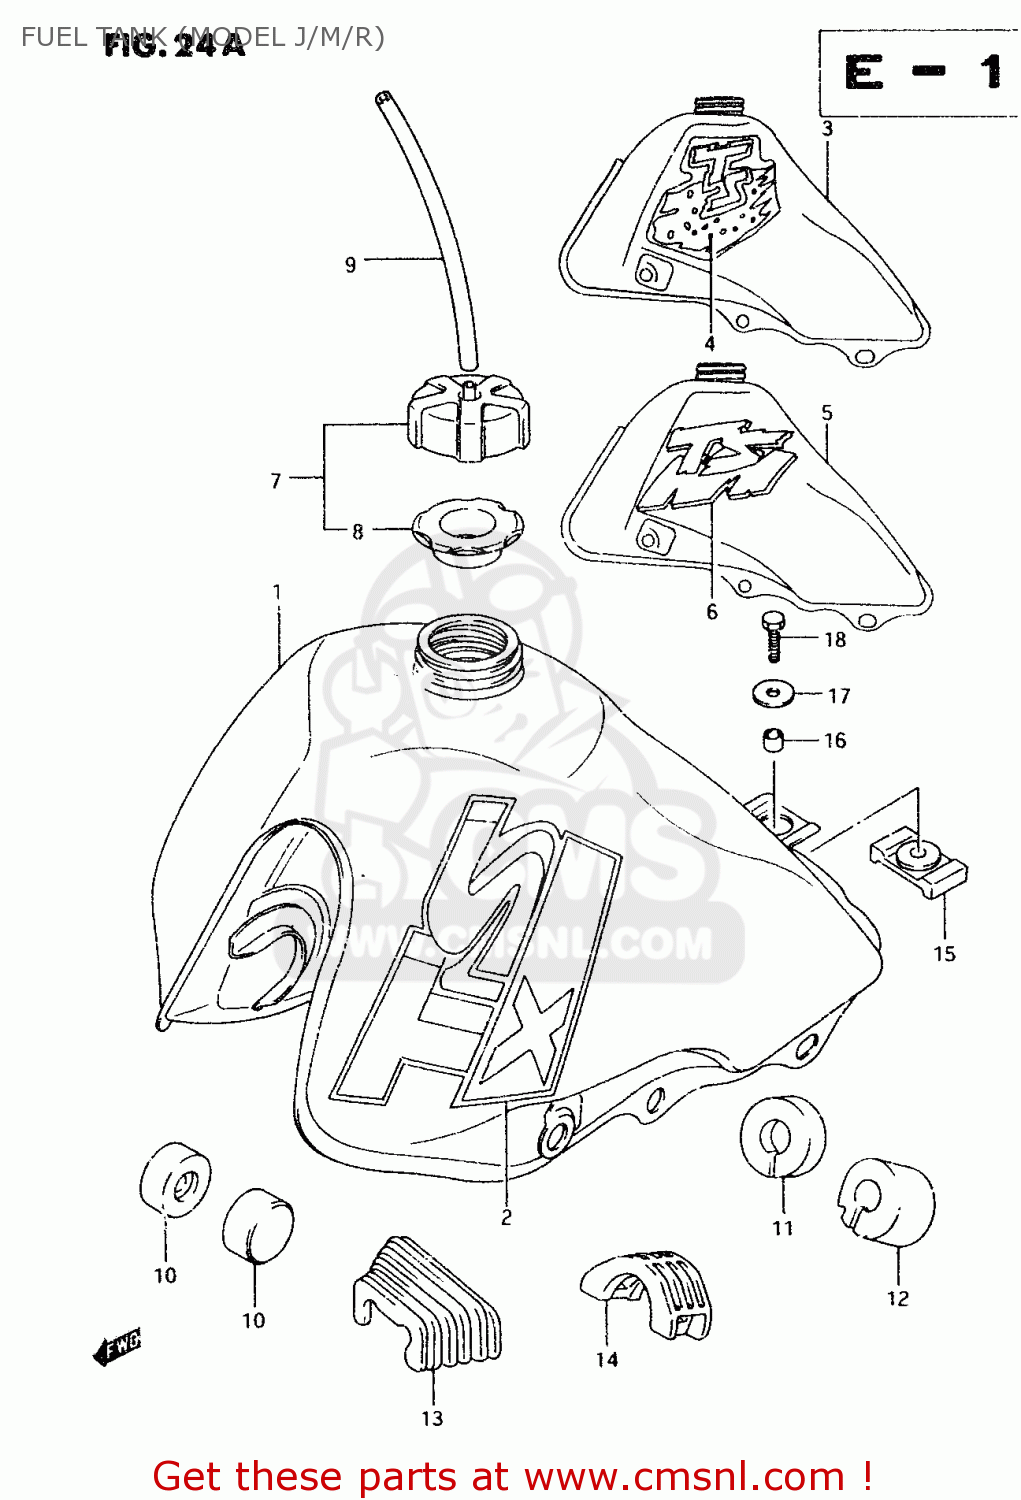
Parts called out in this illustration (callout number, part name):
1	TANK,FUEL
2	TAPE SET, FUEL TANK
3	TANK ASSY, FUEL (WHITE)
4	TAPE SET, FUEL TANK
5	TANK ASSY,FUEL(BLUE)
6	TAPE SET,TANK
7	CAP SET,FUEL TANK
8	GASKET (NAS)
9	HOSE
10	CUSHION
11	CUSHION, LOWER RH
12	CUSHION
13	CUSHION,FUEL TANK LWR
14	CUSHION,FUEL TANK CTR
15	CUSHION,FUEL TANK RR
16	SPACER (6.1X9X9)
17	WASHER(6,5X22X1.6)
18	BOLT
